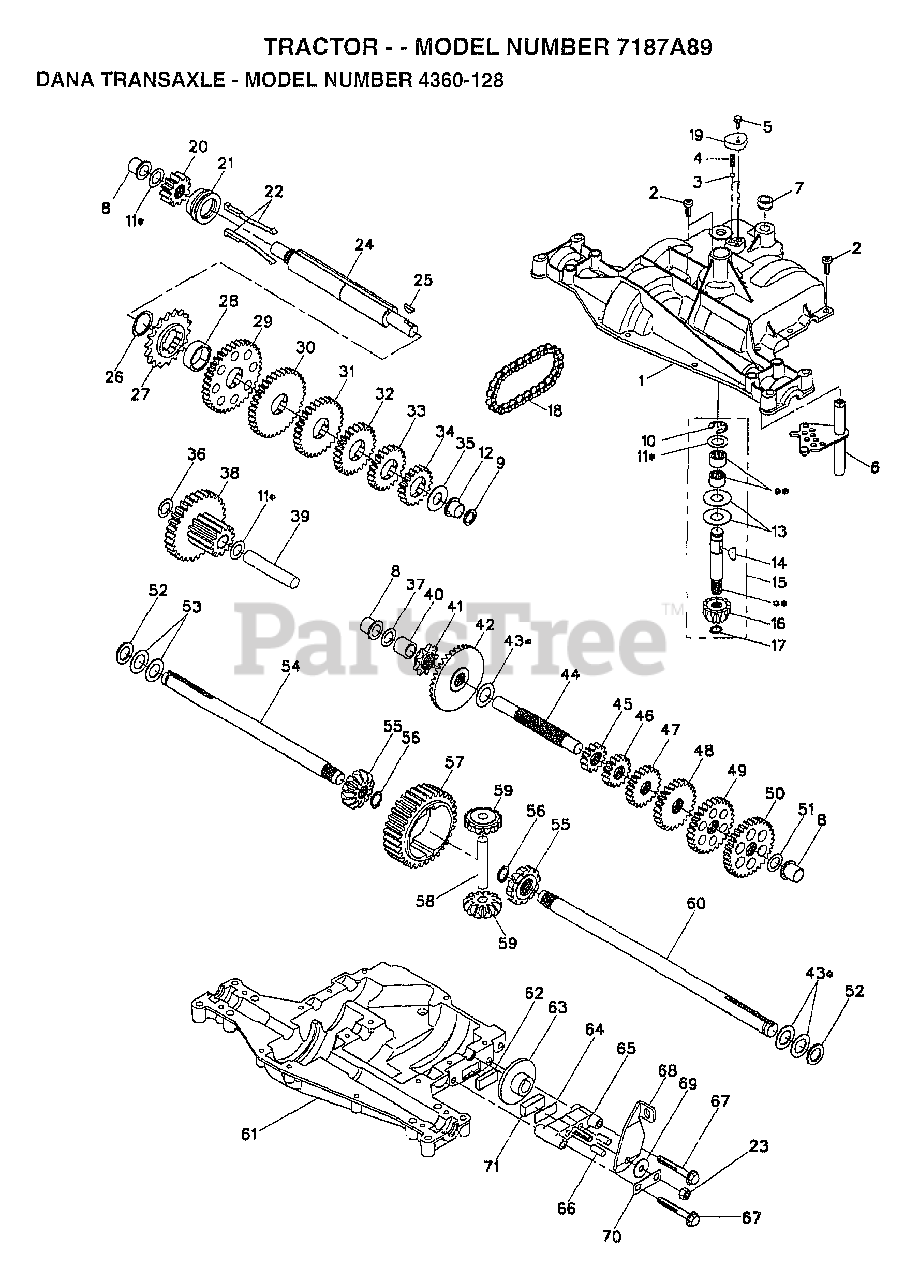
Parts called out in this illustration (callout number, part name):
1	HOUSING.UPPER(5305-P)
4	"SPRING, DETENT LT"
5	SCREW.TAPPING.1/4-20X.734
6	KIT SHIFTER ASM
9	SEAL.OIL.DAN.5508
10	RETAINING RING LT
11	ASM KIT SHIM 4689
12	BEARING.FLNG.5511
13	WASHER T
14	KEY WOODRUFF-DANA
15	INPUT SHAFT KIT 6250
16	PINION.BEVEL.12T(5620)
17	"RING,RETAINING LT"
18	"CHAIN,24 PTCH LT"
19	COVER.DETENT.(5584)
20	GEAR.SPUR.12T.(5627)
21	CLUTCH.COL.5467
22	ASM KIT CLTCH KEY
23	NUT.LOCK.5/16-24
24	SHAFT INTERM DANA
25	WOODRUFF KEY
26	"RING,RETAINING LT"
27	SPROCKET 18T T
28	SPACER YT
29	GEAR SPUR 37 TTH
30	GEAR SPUR 35 TTH
31	GEAR SPUR 30T
32	GEAR 25T LT
33	GEAR SPUR 22 TT
34	SPUR GEAR 19T
35	"WASHER, PLAIN LT"
36	WASHER 045
37	WASHER 031
38	ASSY.GEAR.6153 12T&30T
39	SHAFT IDLER
40	SPACER T
41	SPROCKET 9T LT
42	GEAR.BEVEL.36T(5621)
43	ASM KIT SHIM
44	SHAFT T
45	GEAR SPUR 12 TTH
47	GEAR SPUR 20T
48	"GEAR, SPUR 25T LT"
49	GEAR 28T T
50	"GEAR, SPUR 31T LT"
51	WASHER 060
52	NEOPRENE WASHER
53	WASHER 031
54	AXLE.LH(5528-1)
55	MITER 5270 12T.SPLINED
56	RING.RETAINING.(5270)
58	SHAFT T
59	MITER 5623.12T.IDLER
60	AXLE.RH.(5528-2) DANA
61	HOUSING.KIT (6088)
62	PUCK T
63	BRAKE DISC. T
64	SPACER LT
66	PIN T
67	SCREW.(5562) .5/16-18X2.35
69	WASHER LT
70	BRACKET, ANTI-ROTATION
71	PUCK T
